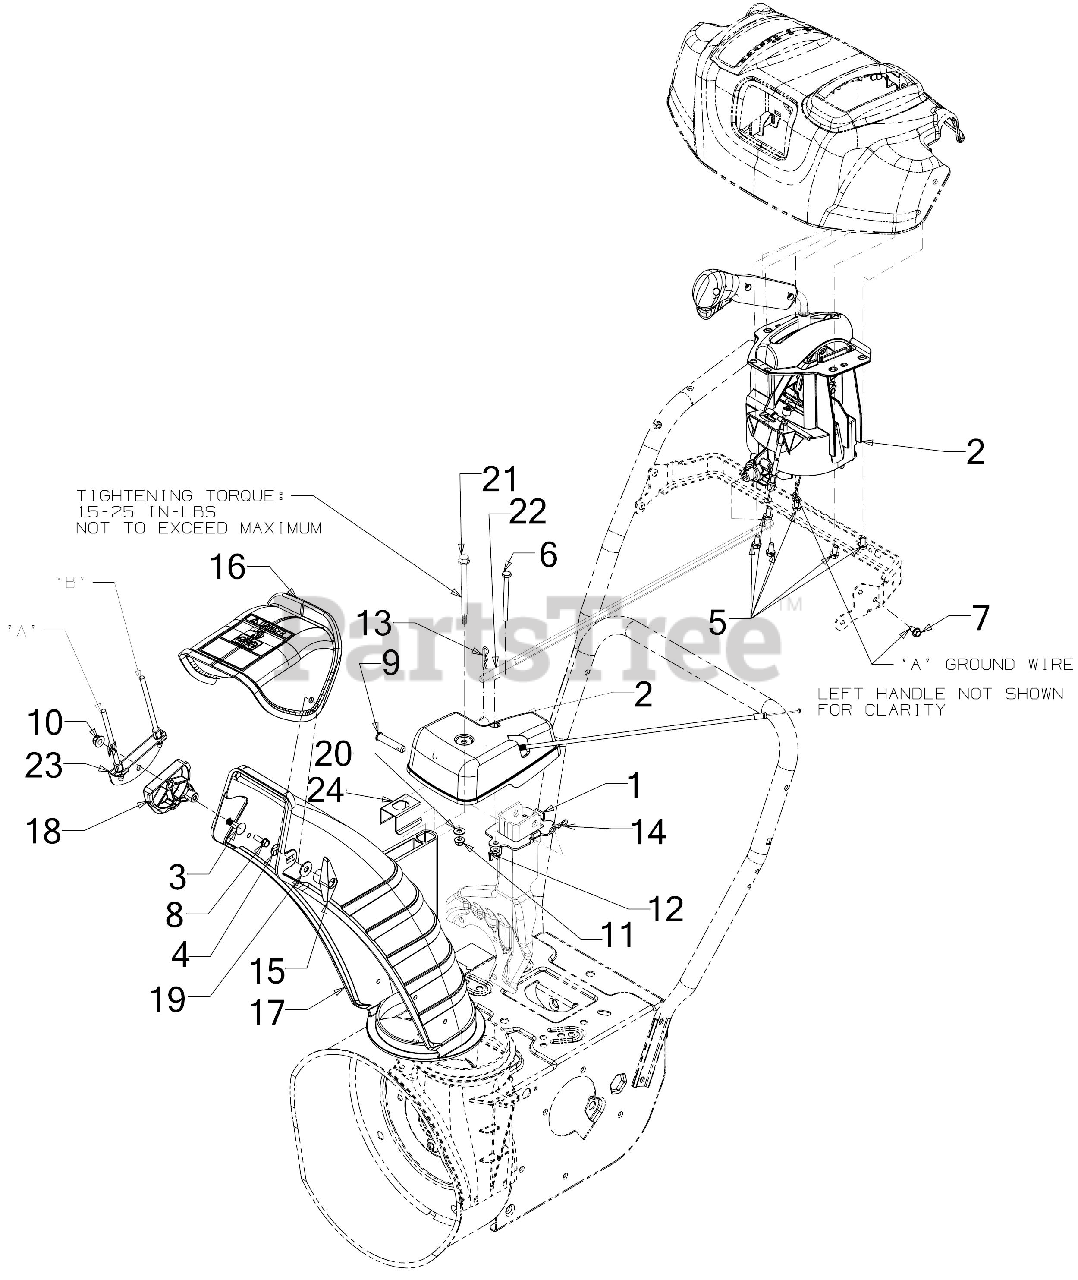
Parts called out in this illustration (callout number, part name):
1	CHUTE SUPPORT BRACKET ASSEMBLY
2	4-WAY CHUTE CONTROL ASSEMBLY
2	CHUTE GEARBOX ASSEMBLY
3	CARRIAGE BOLT 5/16-18 x 1.50
4	CARRIAGE BOLT 5/16-18 x 1
5	HEX SCREW 1/4-15 x .50
6	SCREW 1/4-20 x 3.0 GR5
7	SCREW 1/4-20 X.500
8	SCREW 1/4-15 x .750
9	CLEVIS PIN 3/8 x 1.87
10	FLANGE LOCK NUT 5/16-18
11	FLANGE LOCK NUT
12	WING NUT 1/4-20
13	INTERNAL COTTER PIN
14	BOW TIE COTTER PIN 1/4-5/16
15	WING NUT KNOB
15	HEX NUT
15	STAR KNOB 5/16
16	UPPER REMOTE CHUTE WITH LABEL
17	LOWER CHUTE 5" DIA
18	CABLE CHUTE GUIDE
19	FLAT WASHER
20	FLAT WASHER
21	SHOULDER SCREW
22	CHUTE ROTATION ROD
23	CABLE BRACKET
24	CHUTE BRACKET
